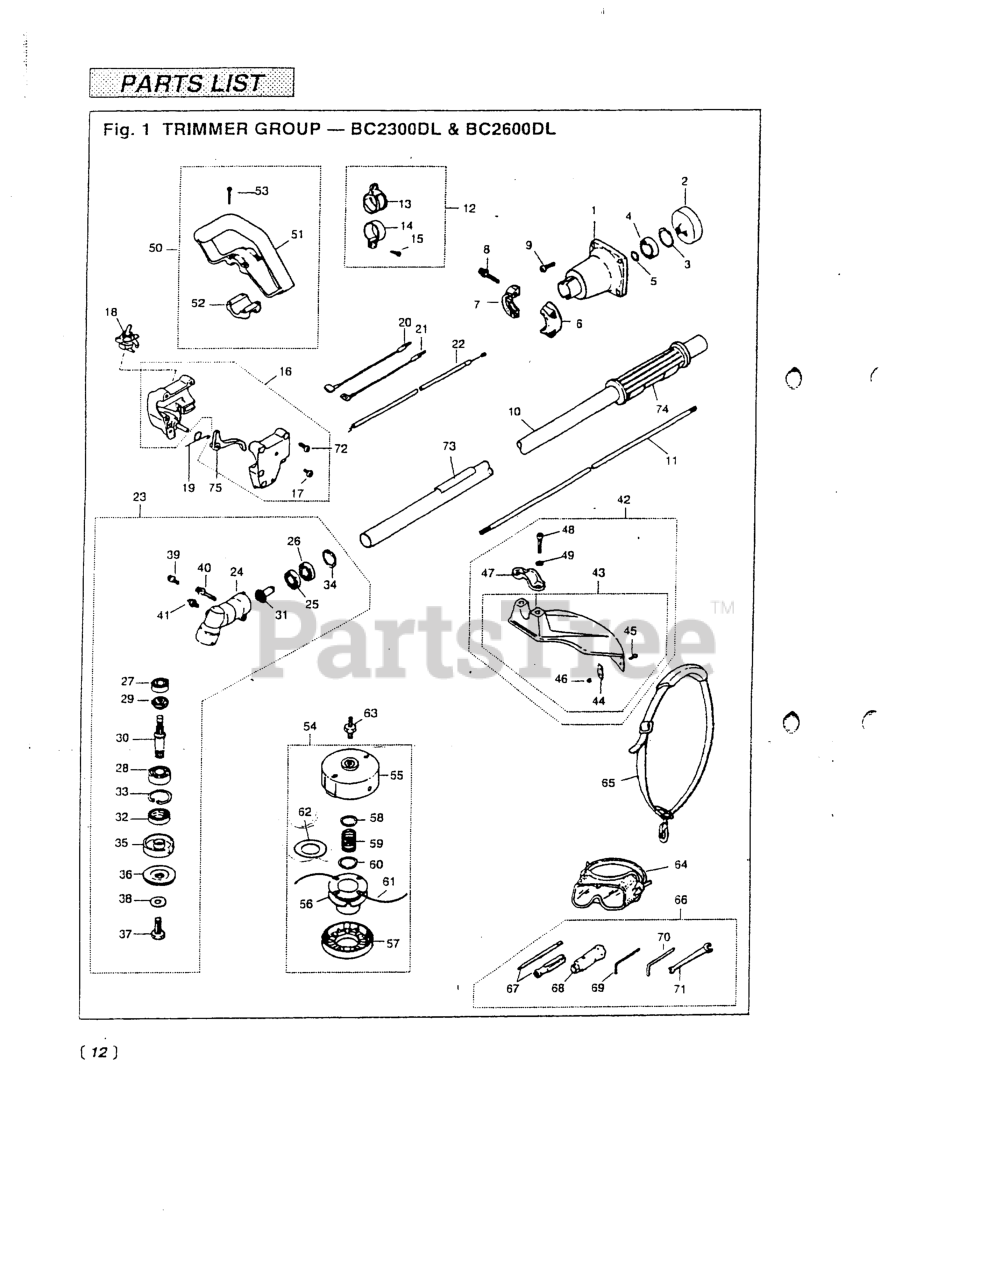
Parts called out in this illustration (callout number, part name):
3	RING, SNAP, M28 x 1.2
4	BEARING
6	CLAMP, LEFT
7	CLAMP, RIGHT
8	BOLT
9	BOLT, M6 X 20
12	HANGER COMPLETE
13	HANGER
14	CLAMP
15	SCREW, M5 x 25
16	THROTTLE LEVER
17	SET SCREW, ANTI-ROTATION
18	SWITCH, STOP
19	SPRING, THROTTLE TRIGGER
20	CORD, RED (LEAD WIRE)
21	CORD, BLACK (LEAD WIRE)
22	CABLE COMP (RPLS 6460- )
23	GEARCASE ASSEMBLY
24	GEARCASE
25	BEARING
26	BEARING
27	BEARING
28	BEARING
29	GEAR
31	PINION
32	SEAL, OIL
33	RING, SNAP
34	RING, SNAP
35	HOLDER (A)
36	HOLDER (B)
38	WASHER
39	BOLT, M5 x 12
40	BOLT, M5 X 25
41	FITTING, GREASE
42	GUARD ASSEMBLY
44	BLADE
45	SCREW, M5 x 12
46	NUT
47	CLAMP
48	BOLT, M6 x 1.30
49	WASHER, M6 X 15
50	HANDLE ASSEMBLY
51	HANDLE
52	CLAMP
53	SCREW, M5 x 35
54	4
58	PLATE, LARGE
60	PLATE, SMALL
61	CORD
62	SPACER
63	ARBOR, 8MM
64	GOGGLE
65	SHOULDER STRAP ASSY
66	TOOL SET
67	SCREWDRIVER
69	WRENCH (TOOL)
70	BAR
71	SPANNER, 8 X 10 (RPLS 2540- )
72	SCREW
75	LEVER, THROTTLE
